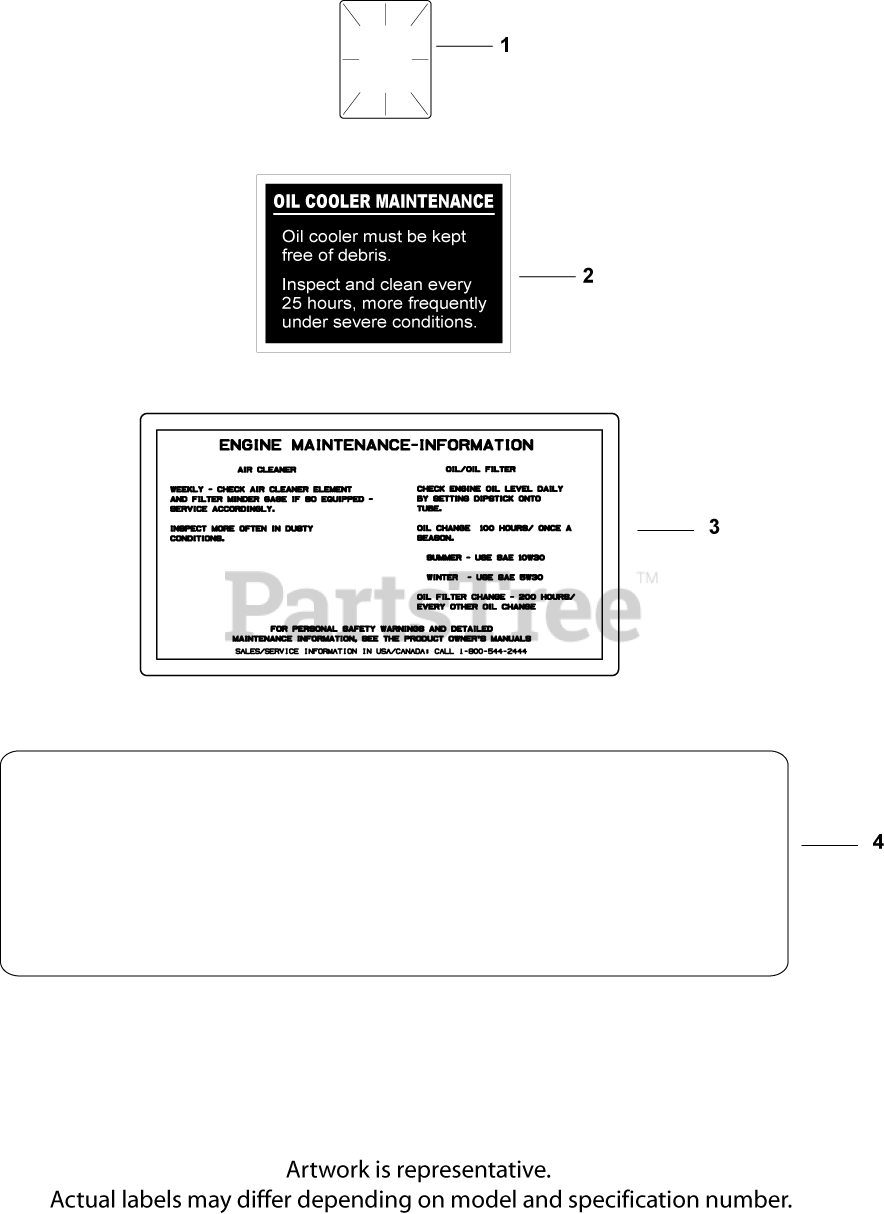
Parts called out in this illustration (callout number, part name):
1	DECAL, CLEAR LAMINATE USE 25 113 70-S
2	DECAL, OIL COOLER - (#DSC)
3	DECAL, ENGINE MAINT. - (#DSC)
4	DECAL, 25 HP - DISCONTINUED
